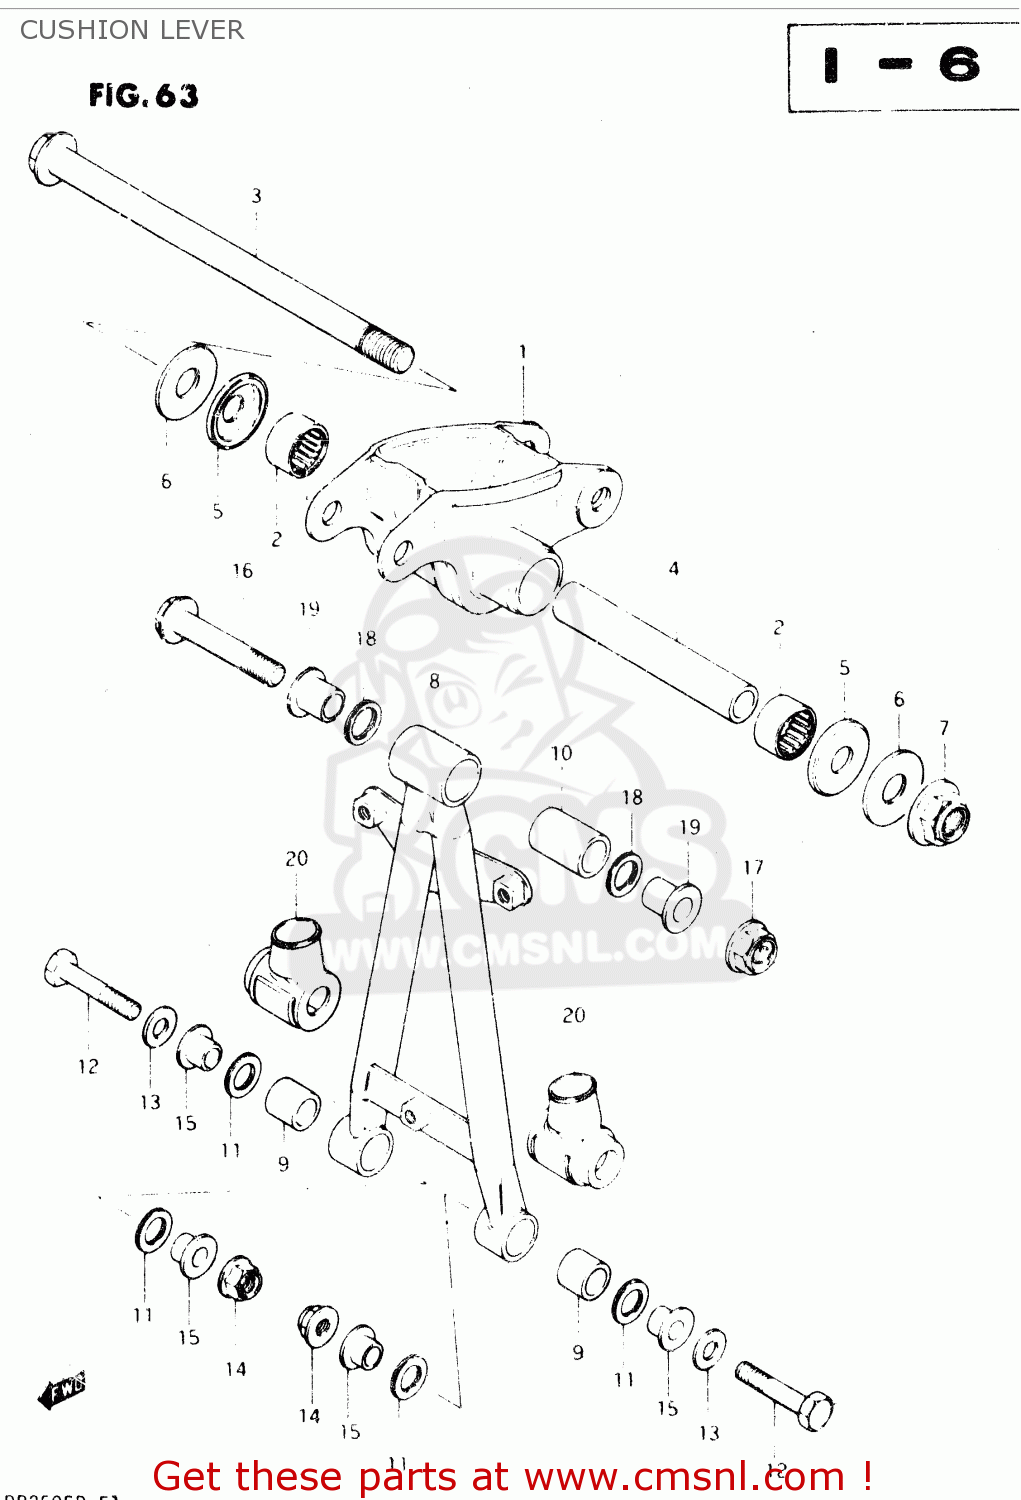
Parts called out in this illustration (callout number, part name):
1	LEVER SET,REAR CUSHION
2	BEARING(17X25X20)
3	SHAFT,REAR CUSHION LEVER
4	SPACER
5	DUST SEAL,RR CUSHION LEVER
6	WASHER
7	NUT 12MM
8	LEVER SET,REAR CUSHION
9	BUSHING
10	BUSH,UPPER
11	DUST SEAL,RR CUSHION LOD LWR
12	BOLT,REAR CUSHION ROD
13	WASHER
14	NUT
15	SPACER,RR CUSHION ROD LWR
16	BOLT(10X65)
17	NUT
18	DUST SEAL,LEVER CUSHION UNIT
19	SPACER,RR CUSHION ROD UPR
20	BOOT,REAR CUSHION ROD,LOWER
